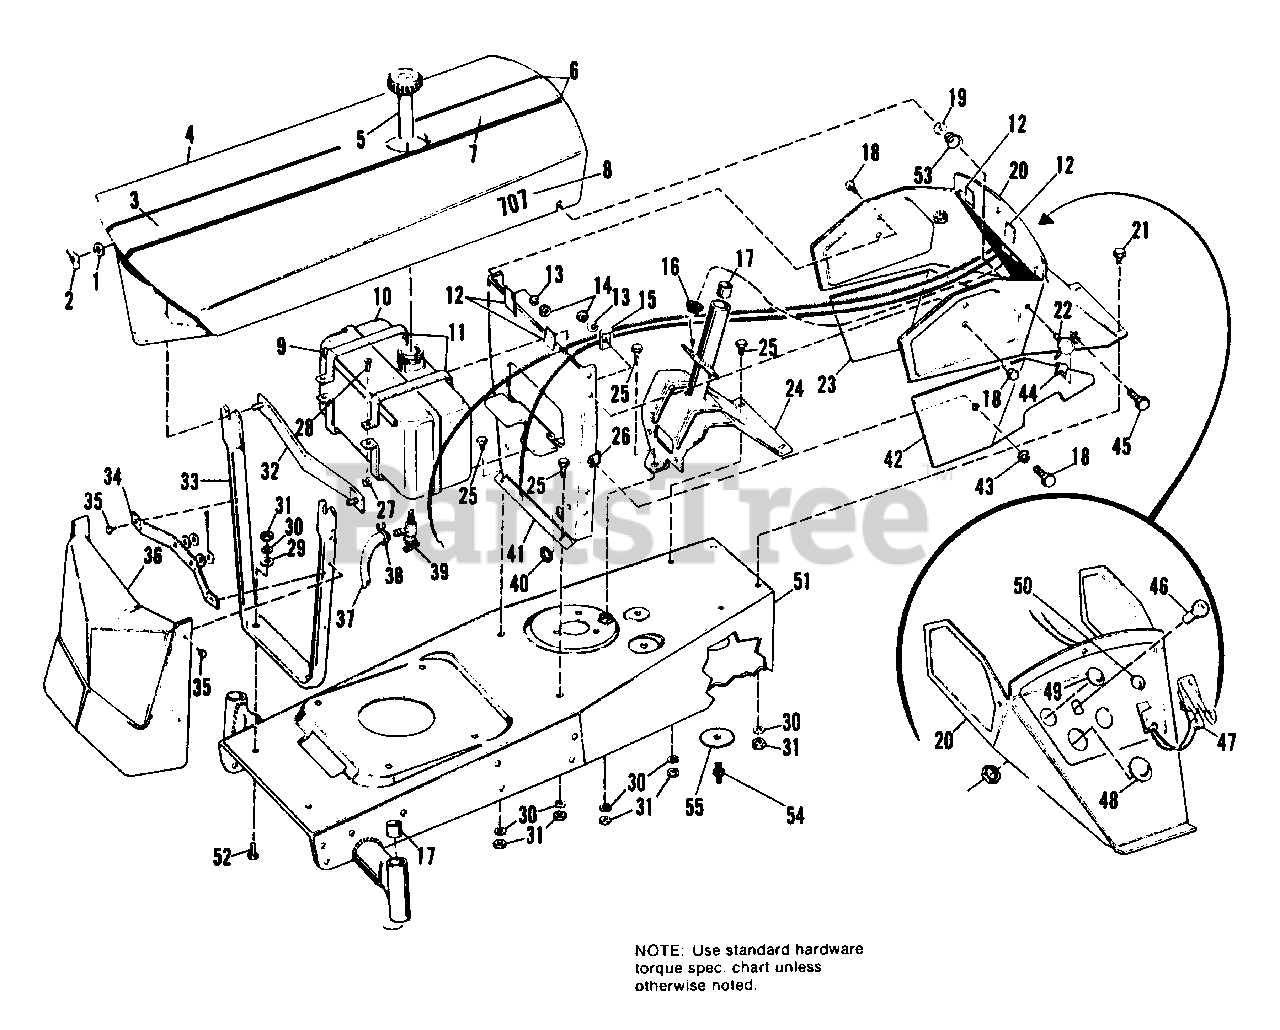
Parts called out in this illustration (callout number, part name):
1	WASHER, Plain, 1/4
2	NUT, Wing, 5/16-18
3	STRIP, Center, Front
4	HOOD ASSY.
5	CAP, Fuel Tank
6	STRIP, Side
7	STRIP, Center, Rear
8	FILM, Simplicity & No.
9	DAMPENER Vibration
10	TANK, Fuel
11	STRAP, Tank
12	GASKET, Felt
13	LOCKWASHER, 1/4
14	NUT, Hex, Full, 1/4-20
16	NUT, Flange, Whizlock, 5/16-18
18	CAPSCREW, Hex Hd., 1/4-20 x 1/2
19	LOCKNUT, Hex, 5/16-18
20	DASH ASSY.
21	SCREW, Special
22	HANDLE ASSY., Tee
23	PANEL, Side, R.H.
24	SUPPORT ASSY., Steering
25	CAPSCREW, Hex Hd., 5/16-18 x 5/8
26	NUT, Speed
27	NUT, Square, 1/4-20
28	SCREW, Fillister Hd., Machine, 1/4-20 x 1-3/4
29	WASHER, Plain, 5/16
30	LOCKWASHER, 5/16
31	NUT, Hex, Full, 5/16-18
32	BAR ASSY., Cross
33	SUPPORT, Hood, Front
34	BRACE, Hood Support
35	SCREW, Hex, Self Tapping, #10 x 1/2
36	GRILLE ASSY.
38	CLAMP, Hose
39	VALVE, Shutoff
41	SUPPORT, Fuel Tank
42	PANEL, Side, L.H.
43	LOCKWASHER, 1/4
44	NUT, Speed
45	SCREW, Hex, Self Tapping, #10 x 5/8
46	SWITCH, Ignition
47	CONTROL, Dual
48	BUTTON, Plug
49	BUTTON, Plug
50	BUTTON, Plug
51	FRAME ASSY.
52	CAPSCREW, Hex Hd., 5/16-18 x 7/8
53	SPRING, Conical
54	FITTING, Grease
55	WASHER, Plain, #10
